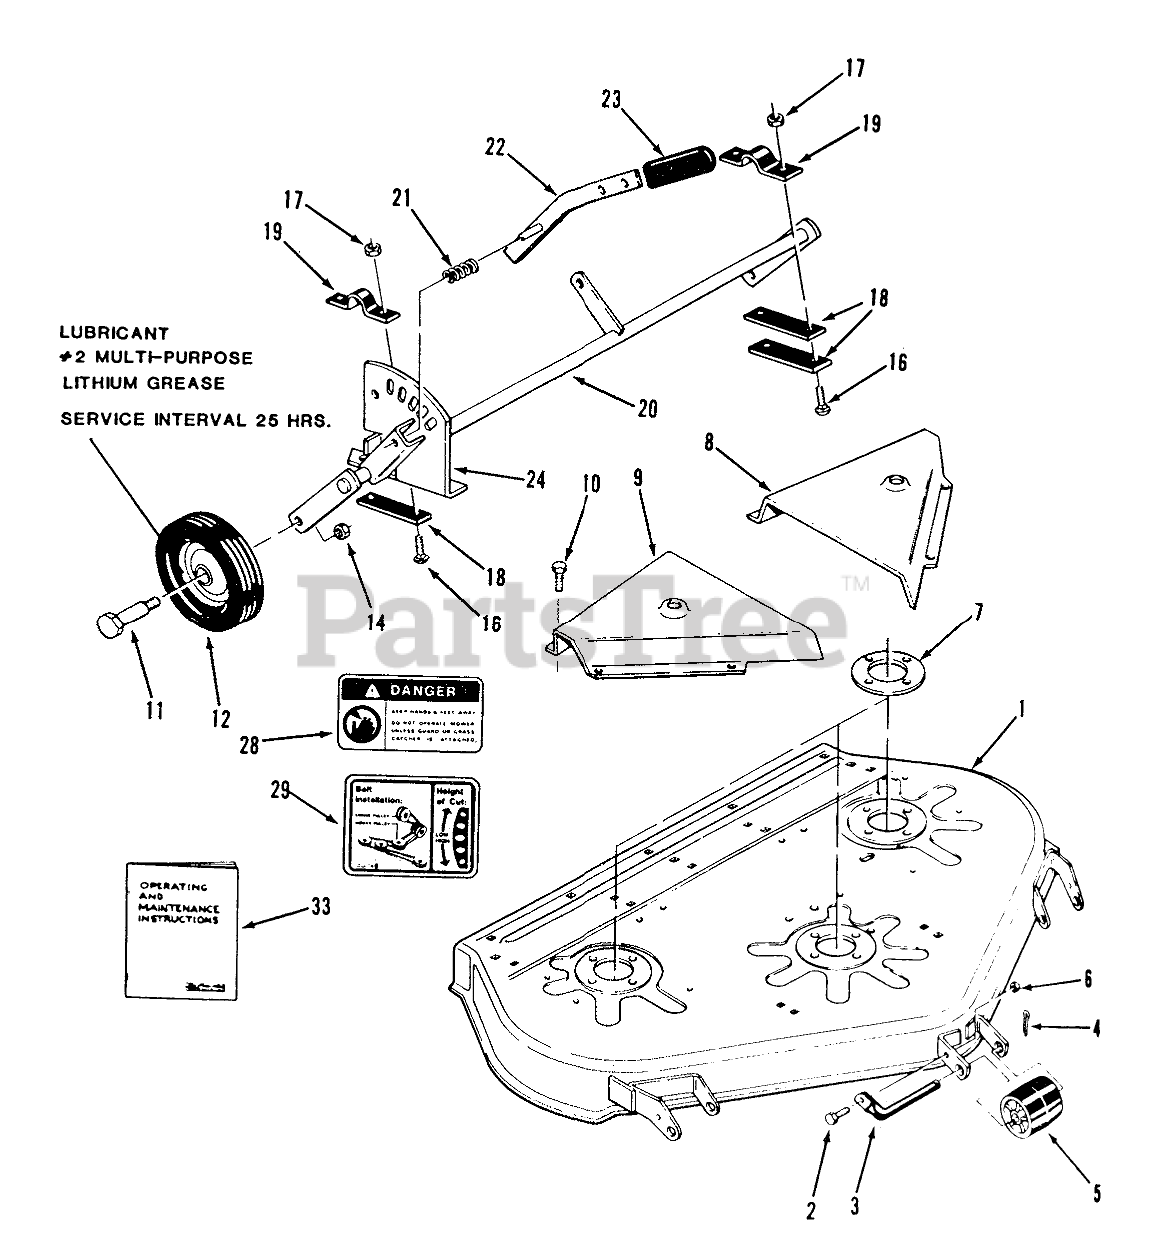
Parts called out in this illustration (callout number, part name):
1	Mower Deck
2	H H C S
3	ROLLER-SHAFT
4	Cotter Pin
5	Roller
6	Nut
7	PLATE-SPINDLE
8	Belt Cover LH
9	Belt Cover RH
10	Bolt
11	BOLT-SHOULDER
12	WHEEL
14	Nut
16	Bolt
17	Nut
18	Bar
20	ASSY GAUGE WHEEL R
21	SPRING-COMPRESSION
22	Lever
24	Quadrant
28	Danger Decal
29	Decal-Height Adj. & Belt Diagram
